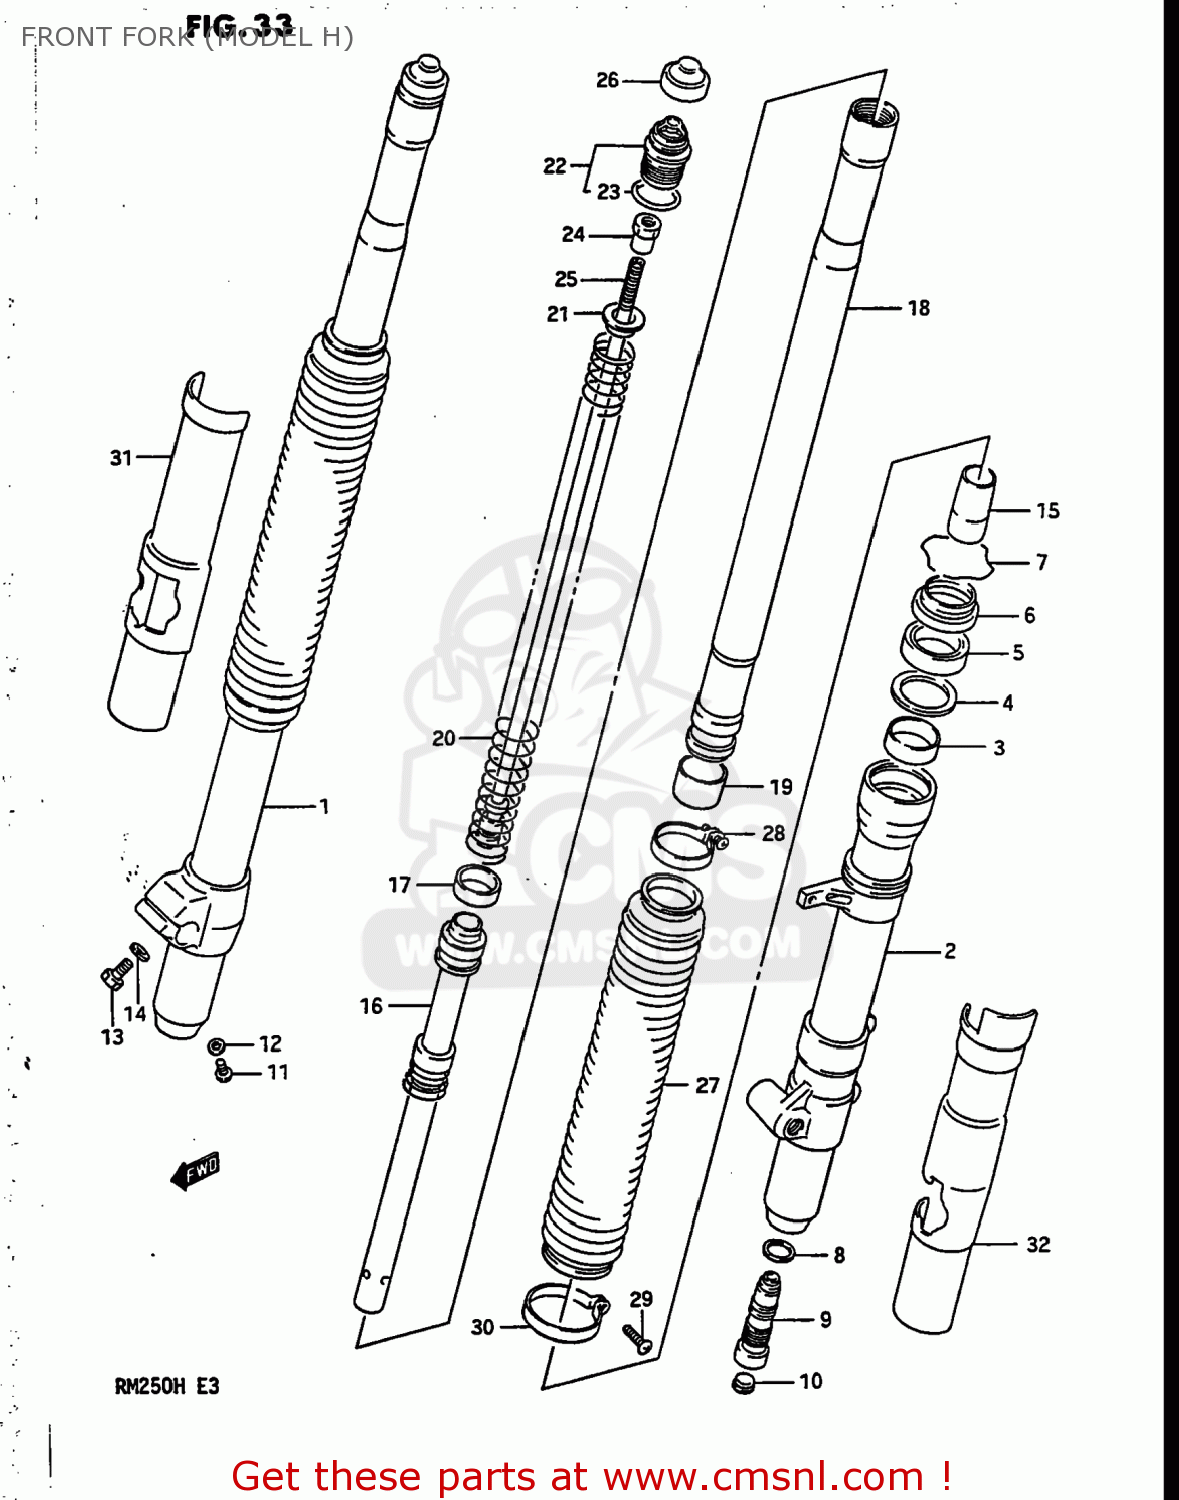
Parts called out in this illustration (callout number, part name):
1	TUBE,OUTER,RIGHT
2	TUBE,OUTER,LEFT
3	METAL,SLIDE
4	WASHER
5	OIL SEAL,FRONT FORK
6	SEAL,DUST
7	RING,STOPPER
8	GASKET
10	CAP,FRONT FORK DF
11	SCREW 4X6
12	GASKET,DRAIN,PLUG (NAS)
13	BOLT
14	WASHER,LOCK
15	PIECE,OIL LOCK
16	CYLINDER,FRONT FORK
17	RING,FRONT FORK PISTON
18	TUBE,FORK,INNER
19	PISTON
20	SPRING,FRONT FORK
21	GUIDE,FRONT FORK SPRING
22	CAP
23	O RING
24	NUT
25	ROD,PISTON
26	CAP
27	BOOT
28	BAND,BOOT,UPPER
29	SCREW,BAND BOOT(3.5X10)
30	BAND,BOOT LWR
31	PROTECTOR,RIGHT
32	PROTECTOR,LEFT
